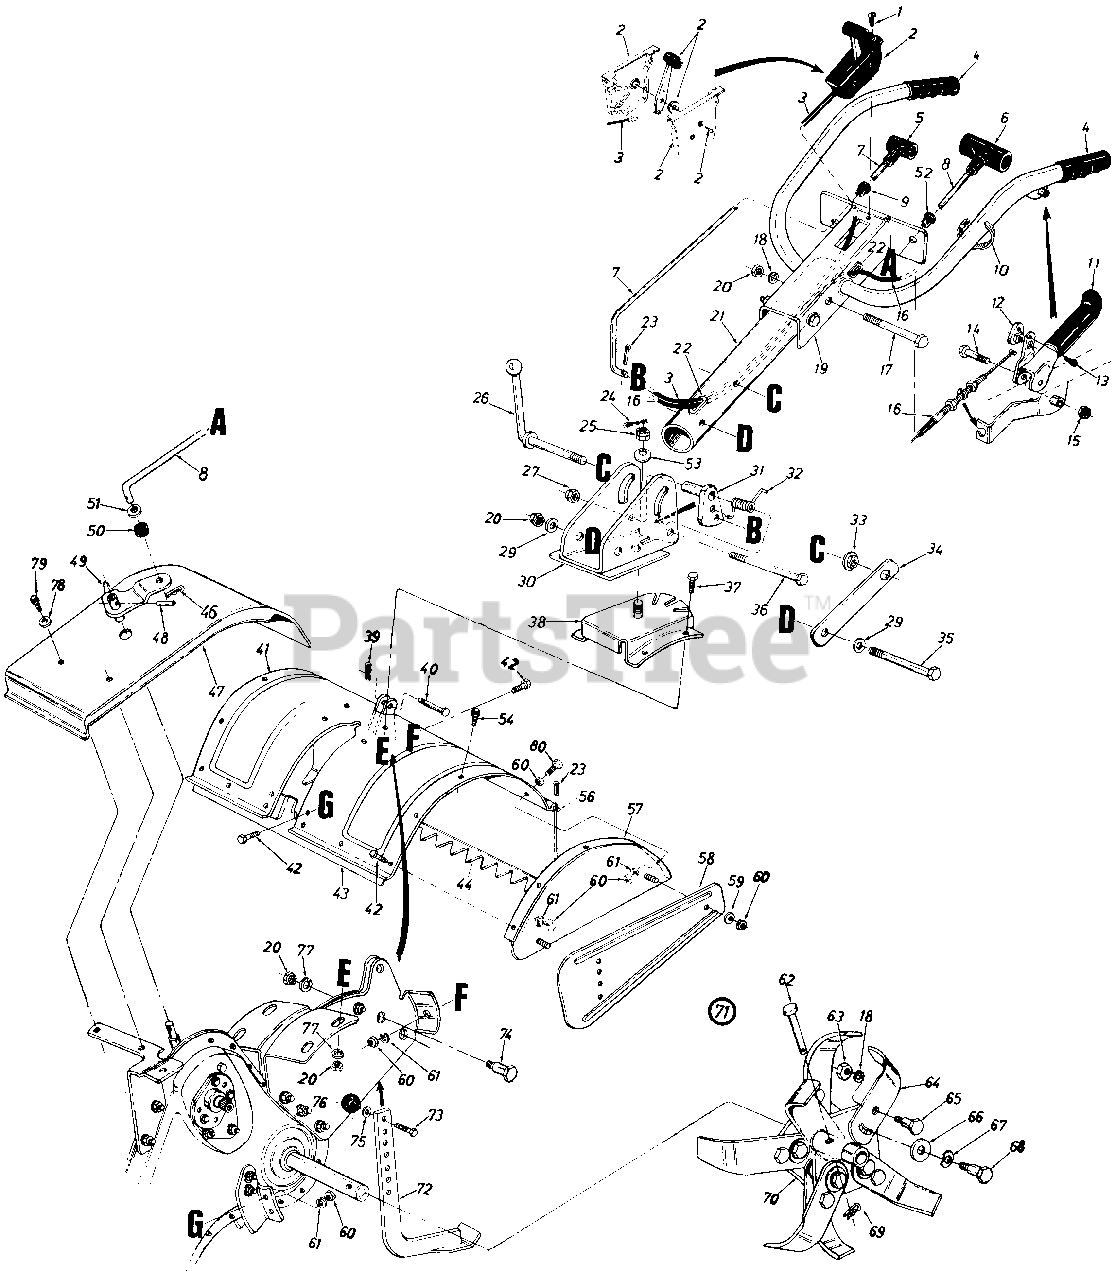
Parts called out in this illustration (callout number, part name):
1	Truss Mach. AB-Tap. Scr. #10 x .50" Lg.
2	Throttle Control Box Ass'y.
3	Throttle Control Wire
4	Handle Grip
5	Small "T" Knob
6	Large"T" Knob
7	Clutch Rod
8	Control Rod 37" Lg.
9	Snap On Bushing 3/8" Dia.
10	Cable Tie-Self Clinching
11	Clutch Grip Ass'y.-L.H.
12	Barrel Cable Hold Down
13	Hex B-Tap Scr. #10 x .44" Lg.
14	Hex Bolt 3/8-16 x 2.0" Lg.*
15	Hex Cent. L-Nut 3/8-16 Thd.
16	Clutch Control Cable 53" Lg.
17	Hex Bolt 3/8-16 x 3.00" Lg.
18	L-Wash. 3/8" I.D.-H.D.
23	Cotter Pin 3/32" Dia. x .75" Lg.*
24	Cotter Pin 3/32" Dia. x 1.25" Lg.*
25	Hex Slotted Nut 5/8-18 Thd.
26	Handle Adj. Crank
27	Hex Cent. L-Nut 3/8-16 Thd.
29	Bell-Wash. .4" I.D. x.87" O.D.
30	Handle Pivot Bracket
31	Positioner Crank Ass'y.
32	Spring Handle Adj.(Torsion)
33	Hex Flange Nut 3/8-24 Thd.
34	Bracket Hex Nut Retainer
35	Hex Bolt 3/8-16 x 3.25" Lg.*
36	Hex Bolt 3/8-16 x 8.00" Lg.- 0 Gr. 8
37	Hex Bolt 3/8-16 x 75n Lg.*
40	Clevis Pin .375" Dia.
43	Bracket Reinforcement-18"
46	Intern. Cotter Pin 5/16" Dia.
49	Shifting Crank Ass'y.
50	Rubber Washer .33" I.D.
51	Fl-Wash. .4" l.D. x 1.25" O.D.
52	Snap On Bushing 1/2n Dia.
53	Bell-Wash. .63" I.D. x 1.25"
54	Hex Wash. Tap Scr.
56	Tiller Flap Rod
57	483 End Cover Ass'y.
60	Hex Nut 5/16-18 Thd.
61	L-Wash. 5/16n l.D.*
62	Clevis Pin .375" Dia.
63	Hex Nut 3/8-24 Thd.*
64	13" Dia. Articulating Tine
65	Shld. Bolt 1/2" Dia. x .175
66	Fl-Wash. .51" l.D. x 1.50"
67	Bell-Wash. .515" l.D. x 1.14"
68	Shld. Bolt 1/2" Dia. x .320
69	Intern. Cotter Pin
70	Tine Adapter Ass'y. 1 8"
71	Tine Ass'y. Comp. 18"
72	Depth Bar Ass'y.
73	Hex Bolt 3/8-16 x .75n Lg.*
74	Shld. Bolt 1/2" l.D. x .62" Lg.
75	Fl-Wash. 818" l.D. x 5/8" O.D.
76	Ball Knob
77	L-Wash. 3/8" I.D.*
78	Fl-Wash. .281" l.D. x .62"
79	Hex Wash. Self-Tap Scr. 1/4-20 x .50" Lg.
80	Hex Bolt 5/16-18 x 11/4" Lg.
